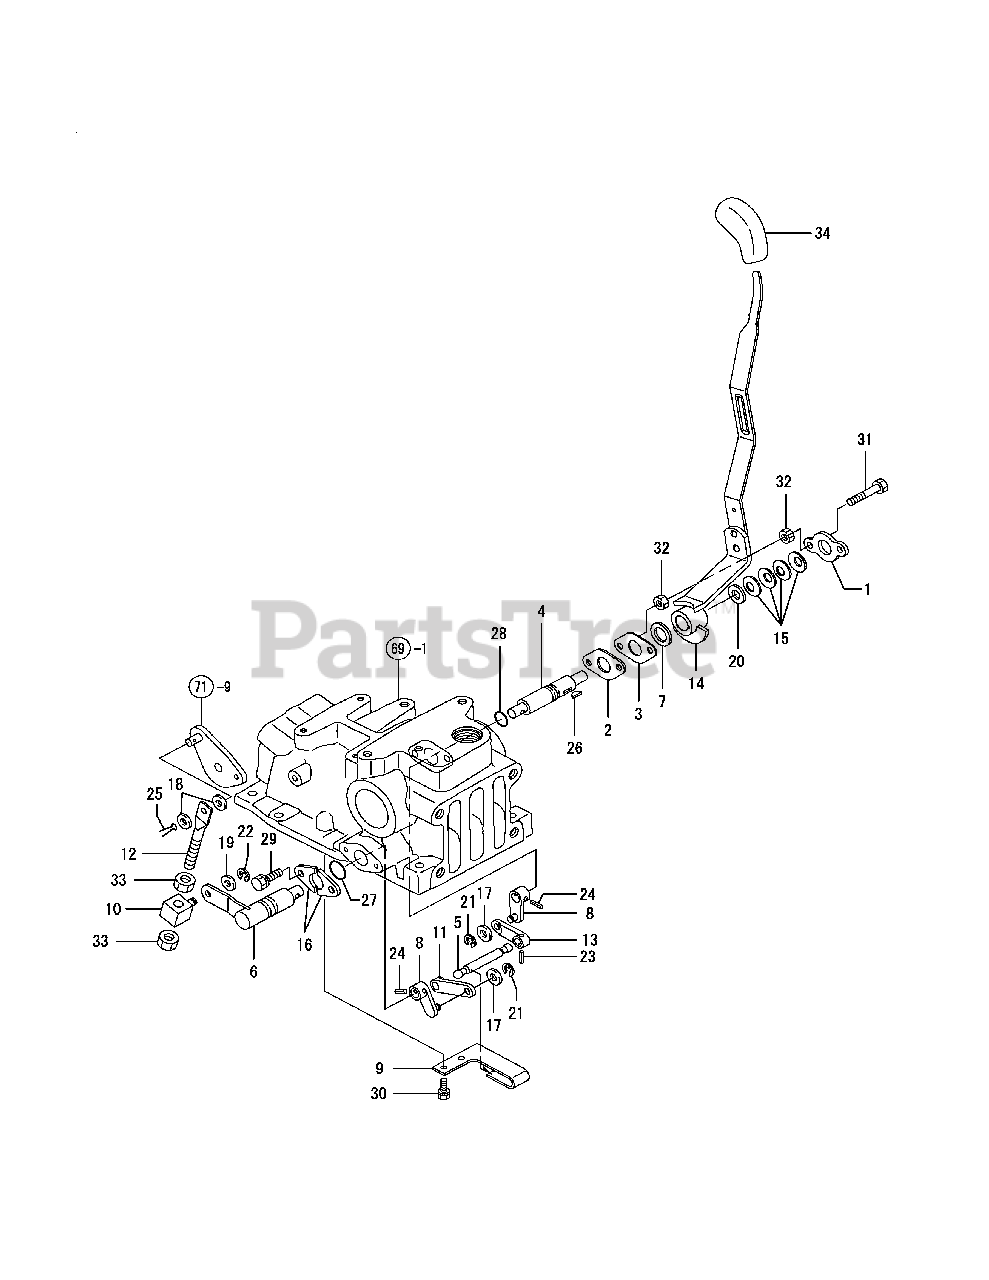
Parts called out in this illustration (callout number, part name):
4	SHAFT, CONTROL LEVER
7	PLATE, FRICTION
8	LEVER, FEED BACK
12	ROD, FEED BACK
14	LEVER, LIFT ARM
18	WASHER 10,POLISHED
19	WASHER 10,POLISHED
20	WASHER 12,POLISHED
23	SPRING PIN 4X16
24	SPRING PIN 5X20
25	COTTER PIN 3.0X20
26	WOODRUFF KEY 3X13
27	O-RING 1A P-15.0
28	O-RING 1A P-15.0
29	BOLT W/WASHER M8X16
30	BOLT W/WASHER M8X16
